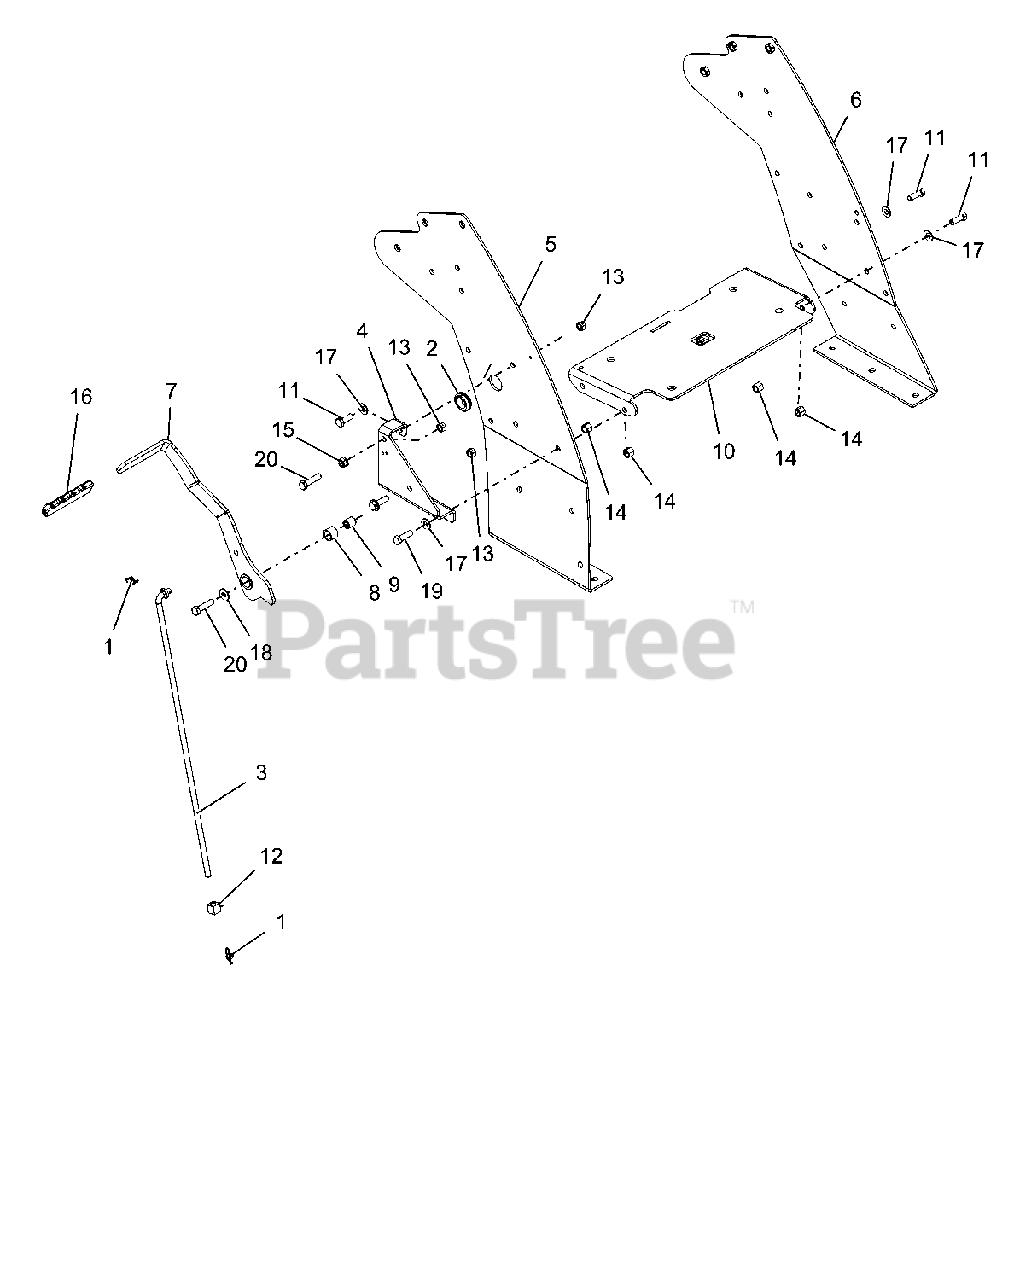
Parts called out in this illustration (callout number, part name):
1	RING, RUE .375 x .054 x 1.254
2	GROMMET:RUB:.88IDx1.38ODX.14GR
3	ROD, DRIVE CONTROL FW
4	LOCATOR, BRAKE ARM WD-RED
5	WLDMT, RH UPRIGHT TOWER-RED
6	WLDMT, LH UPRIGHT TOWER-RED
7	PARK BRAKE WLDT-BLACK
8	PARK BRAKE HANDLE BUSHING
9	PARK, BRAKE LEVER SPACER
10	BRKT, FUEL TANK GRAVELY
11	BLT-HEX .38-16X1.00 GR5 YWZC
12	SWIVEL, 3/8-24
13	NUT-LK-CTR .38-16 YWZC
14	NUT-LK-NYL .38-16 YWZC
15	@NUT-SPNLK-FLG .375-16 YWZC
16	GRIP
17	WSHR-FL-STL.406X.812X.065 YWZ
18	WSHR-FL-STL.38X.875X.083 YWZC
19	BLT-HEX .38-16X1.25 GR5 YWZC
20	BLT-HEX .38-16X1.50 GR5 YWZC
